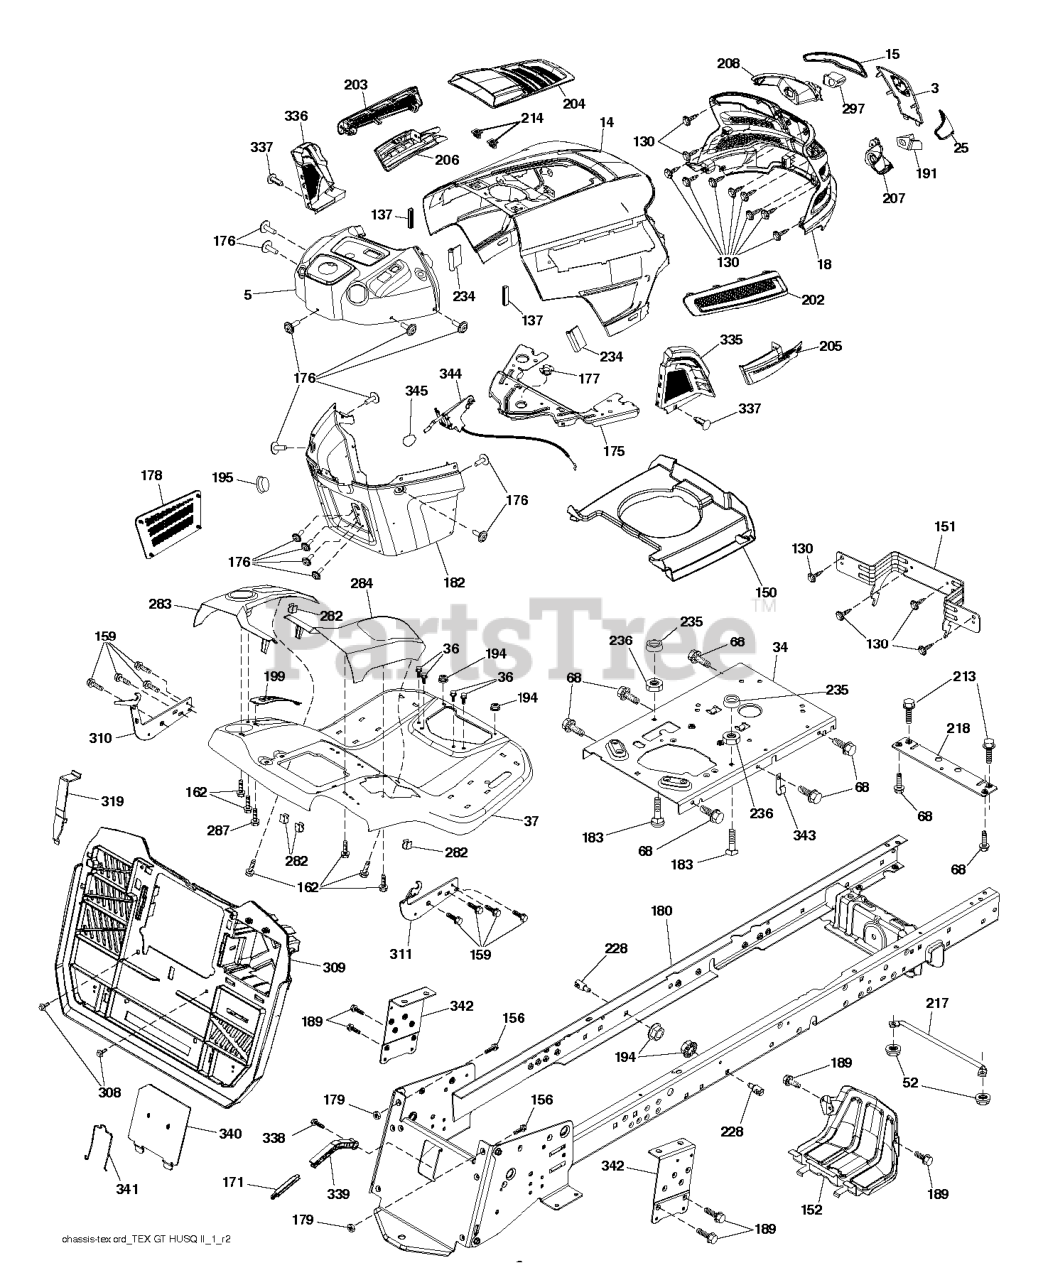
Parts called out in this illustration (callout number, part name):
3	APPLIQUE.SUBASM.GT.HUSQ.II
14	HOOD.ASM.HUSQVARNA.GT.TEX.ORAN
15	LENS.HEADLIGHT.LH.GTII.2011
18	GRILLE.SUBASM.GT.HUSQ.II
25	LENS.HEADLIGHT.RH.GTII.2011
34	PLATE.ENGINE.WELDED.CHASSIS
36	SCREW 5/16"
37	FENDER.TEX.SRD.CRD.BASE
52	LOCKNUT
68	SCREW LT
130	SCREW.#10 X 0.750.BOS
137	BUMPER DASH
150	AIR DUCT.GTV2(1.66"RING HEIGHT
151	BRACKET.PIVOT.HOOD.GT.HUSQ.II
152	SHIELD.BROWNING.PNT.GT.V2
156	BOLT
159	SCREW, 3/8-16X3/4
162	SCREW.HI-LO.CONSOLE
171	EXTENSION.BAGGER.FULL.
175	PLATE.CROSSMEMBER.HUSQ
176	SCREW.#10-24X5/8.RN.QU
177	BUSHING, STEERING
178	CARGO.ASM.NET.TXGT.W/C
182	DASH DASH LOWER
183	BOLT.5/16-18X1-1/4 FULL THD
189	SCREW
191	INSERT.REFLECTIVE.RH.HUSQ.GTII
194	NUT LOCK HEX FLANGE 5/16-18
195	PLUG.HOLE.DASH.LOWER.12V.BLK
199	PLATE DECK LIFT
202	VENT.SIDE.RH.GT.HUSQ.II.
203	VENT.SIDE.LH.GT.HUSQ.II.498
205	SIDE.TRIM.RH.GT.HUSQ.II
206	SIDE.TRIM.LH.GT.HUSQ.II.GRAY
207	BEZEL LIGHT.RH.GT.II.MYLAR
208	BEZEL LIGHT.LH.GT.II.MYLAR
213	BOLT
214	CLIP.RETAINER.TINNER.
217	ROD.PIVOT.HOOD
218	X-PIECE.HOOD.STOP.NON/
228	STUD.FASTNER.W/ANTI-ROTATE
234	BUMPER.HOOD.TEX.HUSQVARNA
235	SPACER FENDER
236	NUT.CENTERLOCK.5/16-
282	CLIP.RETAINER.CONSOLE.LT.HUSQ
283	CONSL.DECKLIFT.LH.SRD.TEX.CRD
284	CONSL.SHFT.PEDAL.RH.SRD.TEXCRD
287	SCREW 1/4X20
297	INSERT.REFLECTIVE.LH.HUSQ.GTII
308	BOLT.5/16-18UNCX3/4 W/SEMS.BLK
319	BRACKET.ACTUATOR.BAGGER.SRD
335	COVER.RH.CLOSE.OUT.BLACK
336	COVER.LH.CLOSE.OUT
337	CLIP.XMAS.TREE.ITW.2622-00
338	BOLT BOLT SHOULDER
339	LEVER.BAGGER.FULL.TEX.
340	DOOR.PNT.BATTERY.TRY.TEX.CRD.
341	LATCH
342	SUPPORT SUPPORT FENDER
343	CLIP CLIP
344	CONTROL.EZ.MULCH.TEX/CRD
345	RP KNOB.OVAL.TAPERED.3/8-16BLK
